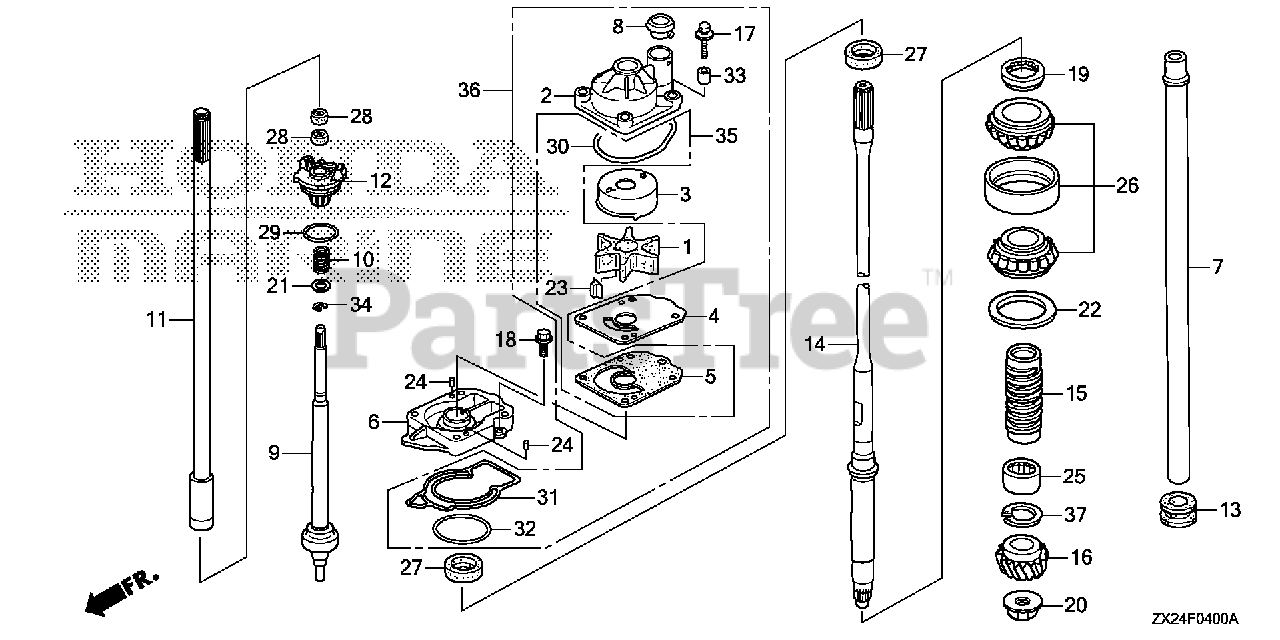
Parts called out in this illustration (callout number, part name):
1	IMPELLER, PUMP
2	HOUSING, IMPELLER
3	LINER, PUMP
4	COVER, IMPELLER
5	GASKET B, IMPELLER
6	HOUSING, WATER PUMP
7	TUBE, WATER (L)
8	RING, WATER TUBE SEAL
9	ROD, SHIFT
10	SPRING, SHIFT ROD
11	ROD A, SHIFT (L)
12	HOLDER, SHIFT ROD
13	GROMMET, EXTENSION CASE
14	SHAFT, VERTICAL (L)
15	SLINGER, OIL
16	GEAR, PINION
17	BOLT-WASHER (8X60)
18	BOLT, FLANGE (6X16) (SUS)
19	NUT, LOCK (68MM)
20	NUT, HEX. (18MM)
21	WASHER, PLAIN (12MM)
22	SHIM A, GEAR (0.10)
22	SHIM B, GEAR (0.15)
22	SHIM C, GEAR (0.30)
22	SHIM D, GEAR (0.50)
23	KEY, WOODRUFF
24	PIN, DOWEL (6X10)
25	BEARING, NEEDLE (30.5X47X37)
26	BEARING, TAPER ROLLER (32X66X49)
27	SEAL, WATER (26X42X7)
28	SEAL, WATER (12X21X6)
30	O-RING, WATER PUMP
31	O-RING, WATER PUMP HOUSING
32	O-RING (65.4X2.4)
33	COLLAR, DISTANCE
34	E-RING (10MM)
35	PUMP KIT, IMPELLER
36	PUMP KIT, IMPELLER
37	CIRCLIP (INNER) (47MM)
